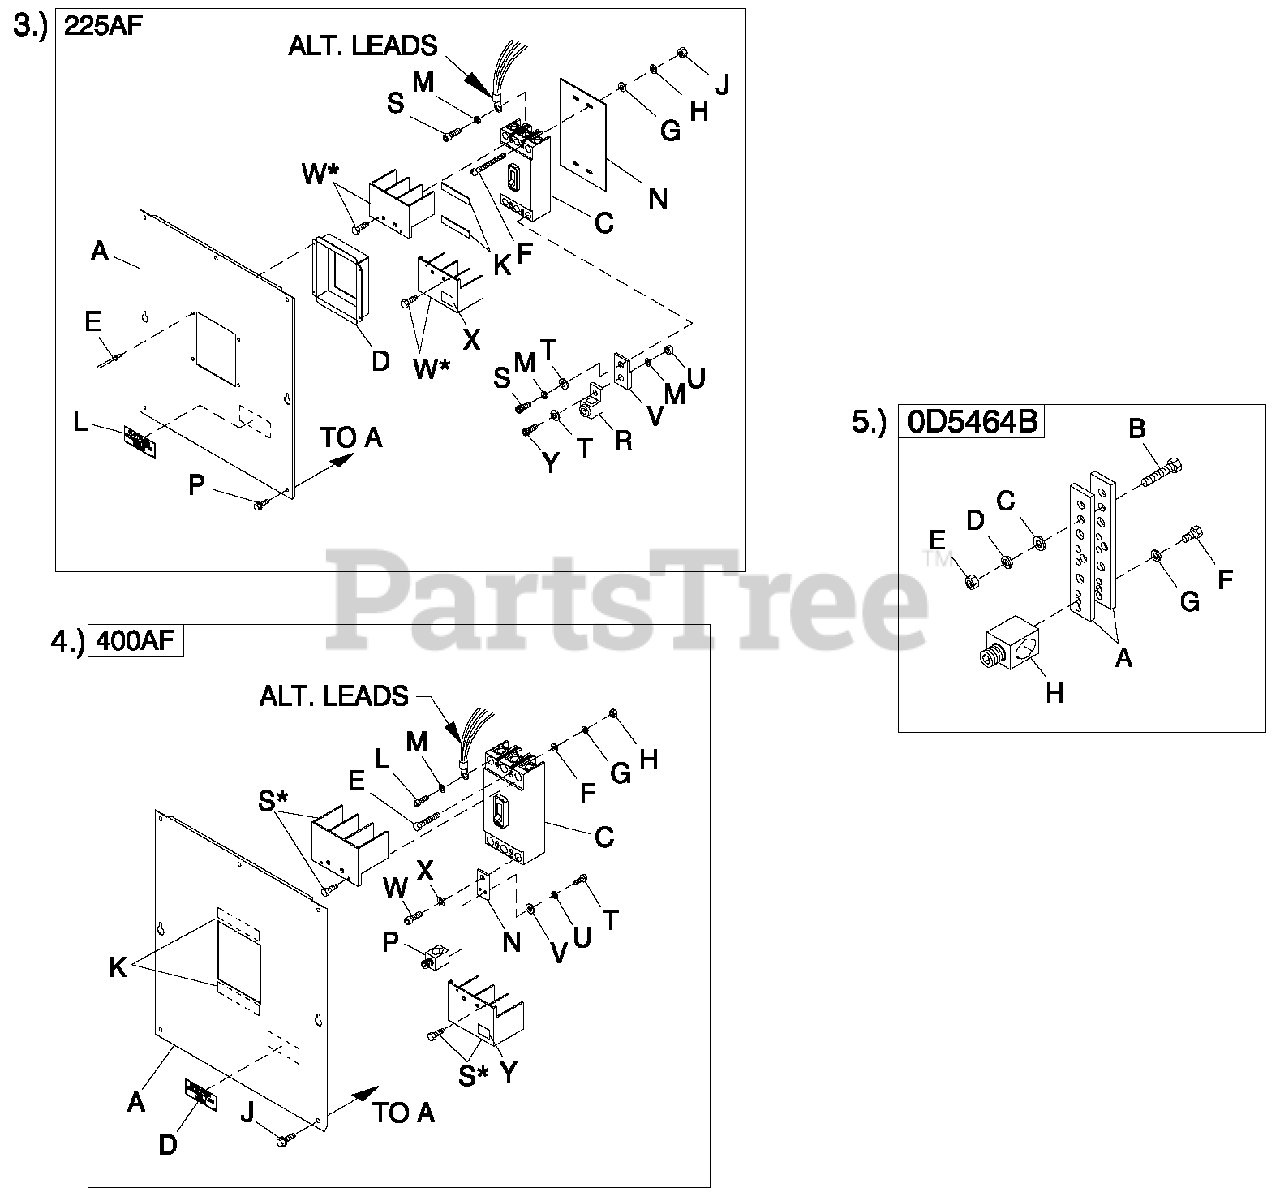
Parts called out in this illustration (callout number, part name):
A	COVER CB C5 225AF
C	CIRCUIT BREAKERS 200A FRAME
D	COVER CB DISH 225AF
E	RIVET POP .125 X .275 SS
F	SCREW RHM #8-32 X 3-1/4
G	WASHER FLAT #8 ZINC
H	WASHER LOCK #8-M4
J	NUT HEX #8-32 STEEL
K	TAPE ELEC 1/2 FOAM
L	DECAL CUSTOMER CONNECT INSIDE
M	WASHER LOCK M8-5/16
N	INSULATOR CB 225AF
P	SCREW THF M6-1 X 16 N WA Z/JS
R	LUG SLDLSS 300 MCM-6 AL/CU
S	SCREW SHC M8-1.25 X 20 G8
T	WASHER FLAT 5/16-M8 ZINC
U	NUT HEX M8-1.25 G8 CLEAR ZINC
V	BUS BAR 200A LUG ADAPTOR
W	TERMINAL COVER CB
X	DECAL TERMINAL SHOCK HZD BI
Y	SCREW SHC M8-1.25 X 25 G12.9
A	COVER CB C5 400AF
C	CIRCUIT BREAKERS 400A FRAME
D	DECAL CUSTOMER CONNECT INSIDE
E	SCREW RHM 10-32 X 4
F	WASHER FLAT #10 ZINC
G	WASHER LOCK #10
H	NUT HEX #10-32 STEEL
J	SCREW THF M6-1 X 16 N WA Z/JS
L	SCREW SHC M10-1.5 X 25 G12.9
M	WASHER LOCK M10
N	BUS BAR CB ADAPTER 225-400 A
P	LUG SLDLSS 600/250-1/0 X 1/4-28
R	WASHER FLAT 3/8-M10 ZINC
S	TERM COVER CB
T	SCREW HHC 1/4-28 X 1/2 G5
U	WASHER LOCK M6-1/4
V	WASHER FLAT 1/4-M6 ZINC
W	SCREW SHC M10-1.5 X 25 G12.9
X	WASHER LOCK M10
Y	DECAL TERMINAL SHOCK HZD BI
A	COVER CB C5 800AF
C	CIRCUIT BREAKERS 800A FRAME
D	INSULATOR CB 800AF
E	SCREW RHM 1/4-20 X 3-1/2
F	WASHER FLAT 1/4-M6 ZINC
G	WASHER LOCK M6-1/4
H	NUT HEX 1/4-20 STEEL
J	SCREW THF M6-1X16 N WA Z/JS
L	SCREW SHC M10-1.50 X 40 G12.9
M	WASHER FLAT 3/8-M10 ZINC
N	WASHER LOCK 3/8
P	NUT HEX M10-1.5 G8 YEL CHR
R	LUG SLDLSS 3/0-400X3 MCM AL/CU
S	SCREW SHC M6-1.0 X 50 G8.8
T	DECAL CUSTOMER CONNECT INSIDE
U	TERM COVER VITZROTECH 400AF CB
V	DECAL TERMINAL SHOCK HZD BI
W	WASHER LOCK M6-1/4
A	BUS BAR NEUTRAL BLOCK 390
B	SCREW HHC M8-1.25 X 45 G8.8 FT
C	WASHER FLAT 5/16-M8 ZINC
D	WASHER LOCK M8-5/16
E	NUT HEX M8-1.25 G8 YEL CHR
F	SCREW HHC 1/4-28 X 3/4 G5
H	LUG SLDLSS 600/250-1/0X1/4-28
